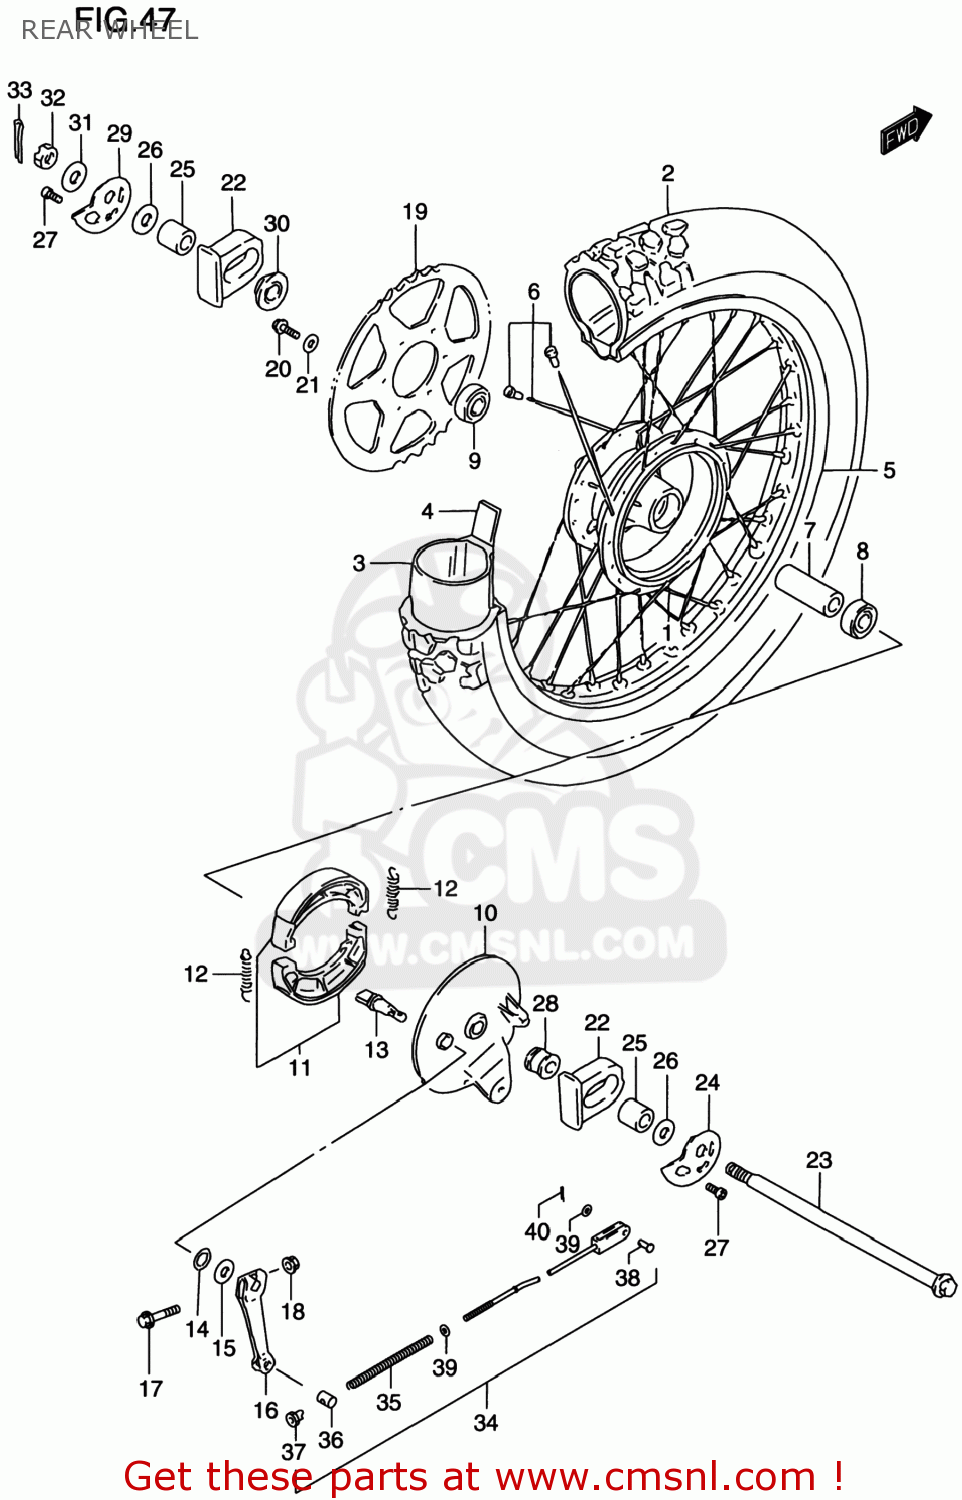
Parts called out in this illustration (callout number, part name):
1	HUB,RR WHEEL
2	TIRE,RR(100/90-18 56P)
3	TUBE ASSEMBLY,WHEEL,INNER
4	PROTECTOR,INNER TUBE
5	RIM,RR WHEEL(18X2.15 AL)
6	SPOKE ASSY,RR WHEEL
7	SPACER(15.3X21.7X107.5)
8	BEARING
9	BEARING
10	PANEL,RR BRAKE ANCHOR
11	SHOE SET,BRAKE (NAS)
12	SPRING(L:34)
13	CAM,BRAKE
14	O RING(D:2.5,ID:13.8)
15	WASHER(14.5X22X1.6)
16	LEVER,RR BRAKE CAM
17	BOLT
18	NUT
19	SPROCKET,RR(NT:45)
20	BOLT(8X30)
21	WASHER
22	CAP,RR SWINGING ARM
23	AXLE,RR
24	ADJUSTER,CHAIN,R
25	SPACER,CHAIN ADJUSTER
26	WASHER(15.5X30X3.2)
27	BOLT,CHAIN ADJUSTER
28	SPACER,RR AXLE,R
29	ADJUSTER,CHAIN,L
30	SPACER,RR AXLE,L
31	WASHER
32	NUT
33	COTTER PIN
34	ROD ASSY,RR BRAKE
35	SPRING
36	PIN(13X18)
37	NUT
38	PIN(L:13.5)
39	WASHER
40	PIN 20X20
